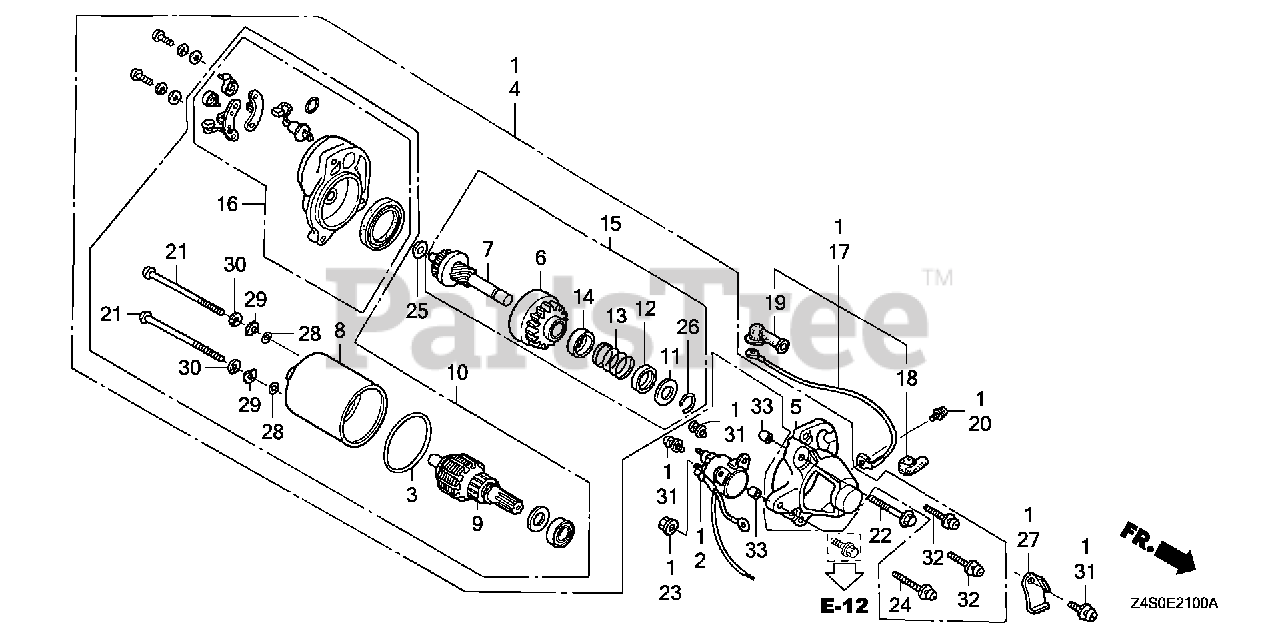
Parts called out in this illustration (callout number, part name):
1	STARTER MOTOR ASSY.
2	SWITCH, STARTING MAGNET
4	STARTER MOTOR UNIT (SM-11205) (181MM)
5	COVER, GEAR
6	PINION ASSY.
7	SHAFT UNIT, GEAR
8	YOKE ASSY.
9	ROTOR ASSY.
10	MOTOR ONLY
11	PIECE A, STOPPER
12	PIECE B, STOPPER
13	SPRING, RETURN
14	COVER, SPRING
15	GEAR ASSY.
16	BRACKET, FR.
17	WIRE, MAGNETIC SWITCH
18	COVER, MAGNETIC SWITCH
19	COVER, STARTER MOTOR TERMINAL
20	SCREW-WASHER (5X8)
21	BOLT, SETTING
22	BOLT, FLANGE (6X32) (CT200)
23	NUT-WASHER (6MM)
24	SCREW-WASHER (5X30)
25	WASHER, PINION
26	CIRCLIP (10.2MM)
27	HOLDER, HARNESS
29	WASHER, SPECIAL
30	WASHER, SPRING
31	SCREW-WASHER (5X14)
32	SCREW-WASHER (5X20)
33	PIN, DOWEL (8X10)
